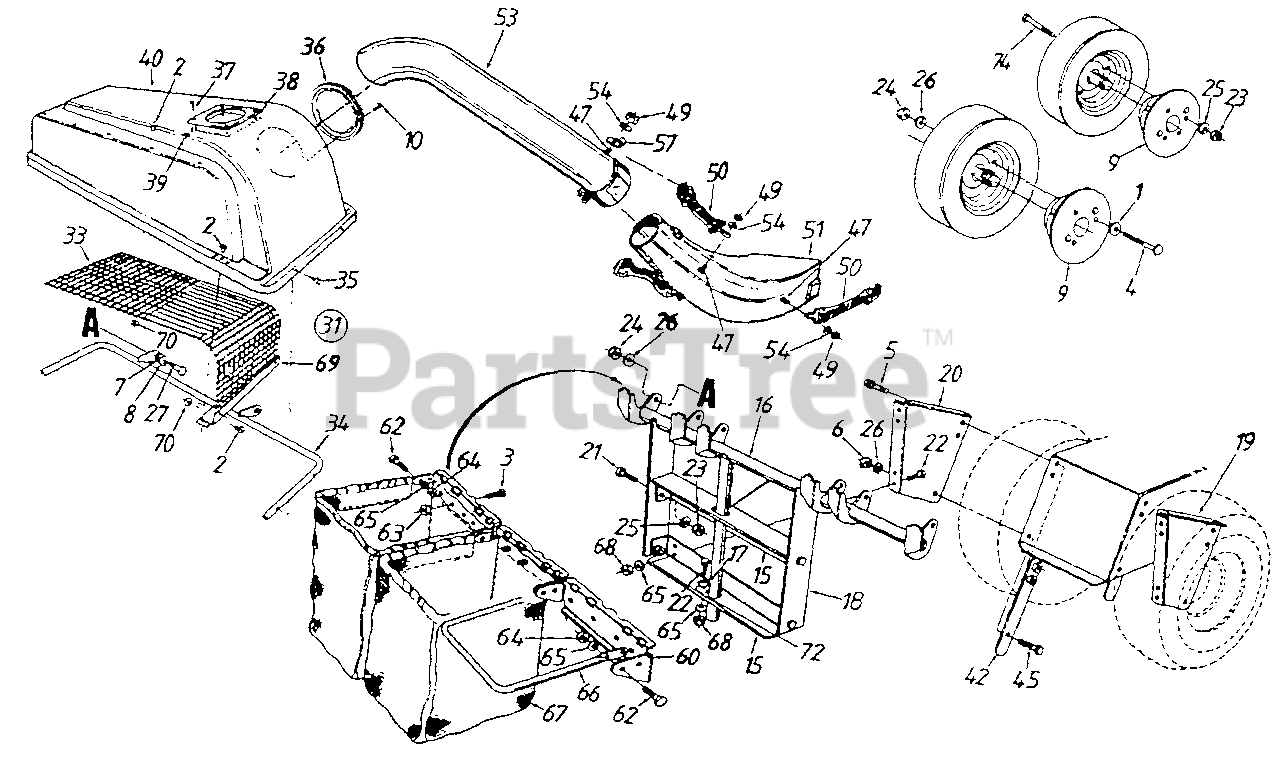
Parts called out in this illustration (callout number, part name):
1	Fl-Wash .385" I.D.
2	Pop Rivet
3	Truss Mach. Scr. #10-24 x .5"
4	Hex Bolt 3/8-16 x 4.5" Lg.
5	Hex Wash. Hd. Tap Scr. 5/16-18 x .62"
6	Hex Nut 3/8-24 Thd.
7	Bell-Wash .515" I.D.
8	Fl-Wash .510" I.D.
22	Hex Bolt 1/4-20 x .62" Lg.- Grade 5
23	Hex Nut 5/16-18 Thd.
24	Hex Nut 3/8-16 Thd.
25	L-Wash. 5/16" I.D.
26	L-Wash. 3/8" I.D.
27	Shld. Bolt 3/8-16 x .500" Dia.
31	Catcher Cover Ass'y. Comp.
33	Screen
36	Tube Seal
37	Truss Mach. B-Tap Scr. #10 x .5" Lg.
38	Plastic Plate
39	Speed Nut
40	Grass Catcher Cover
47	Hex Bolt 1/4-20 x .50" Lg.
49	Hex ins. L-Nut 1/4-20 Thd.
50	Retainer Strap Ass'y.
51	Discharge Chute
53	Catcher Elbow Tube
54	L-Wash .270" I.D. x .57" O.D.
57	Retainer Hook Brkt.
62	Hex Bolt 1/4-28 x .88" Lg.
63	Hex Sems Nut #10-24 Thd.
64	Hex Nut 1/4-28 Thd.
65	L-Wash. 1/4" I.D.
66	Catcher Bag Frame
67	Grass Catcher Bag
68	Hex Nut 1/4-20 Thd.
74	Hex Bolt 5/16-18 x 4" Lg.
